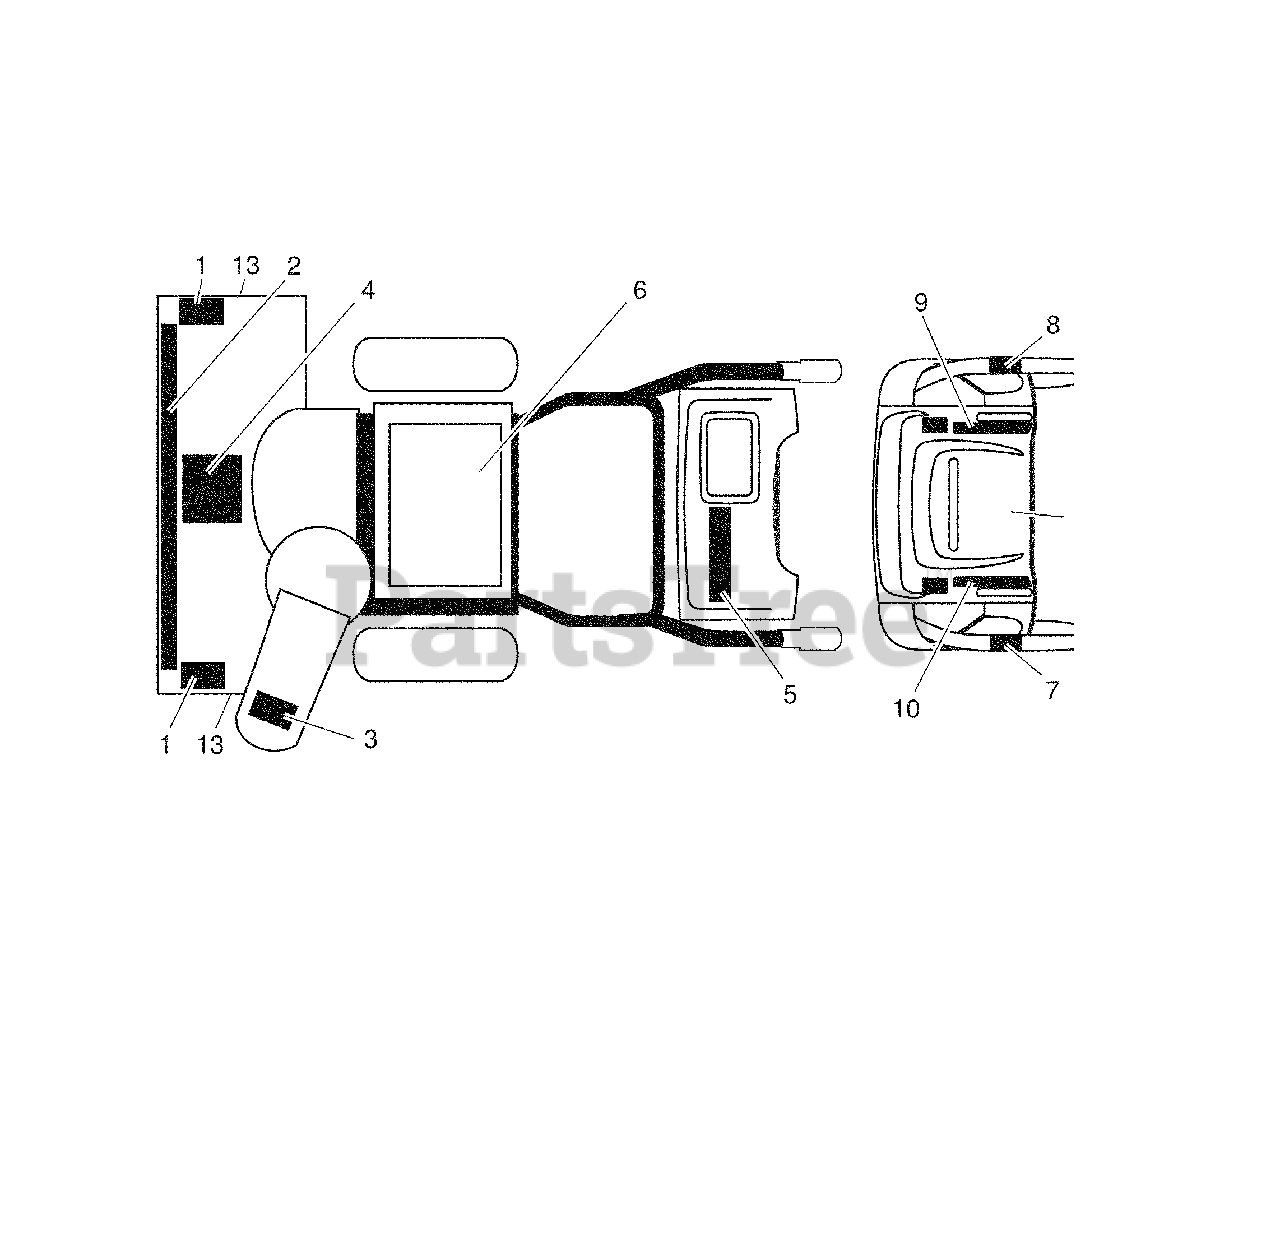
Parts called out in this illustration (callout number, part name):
1	Decal, Danger
2	Decal, Husqvarna
3	Decal, Danger, Deflector
4	Decal, Danger
5	Decal, Husqvarna, 10527SBE
6	Decal, Instruction
7	Decal, Traction Lever
8	Decal, Auger Lever
9	Decal, Speed Control
10	Decal, Remote Deflector
13	Decal, Husqvarna, Crown
